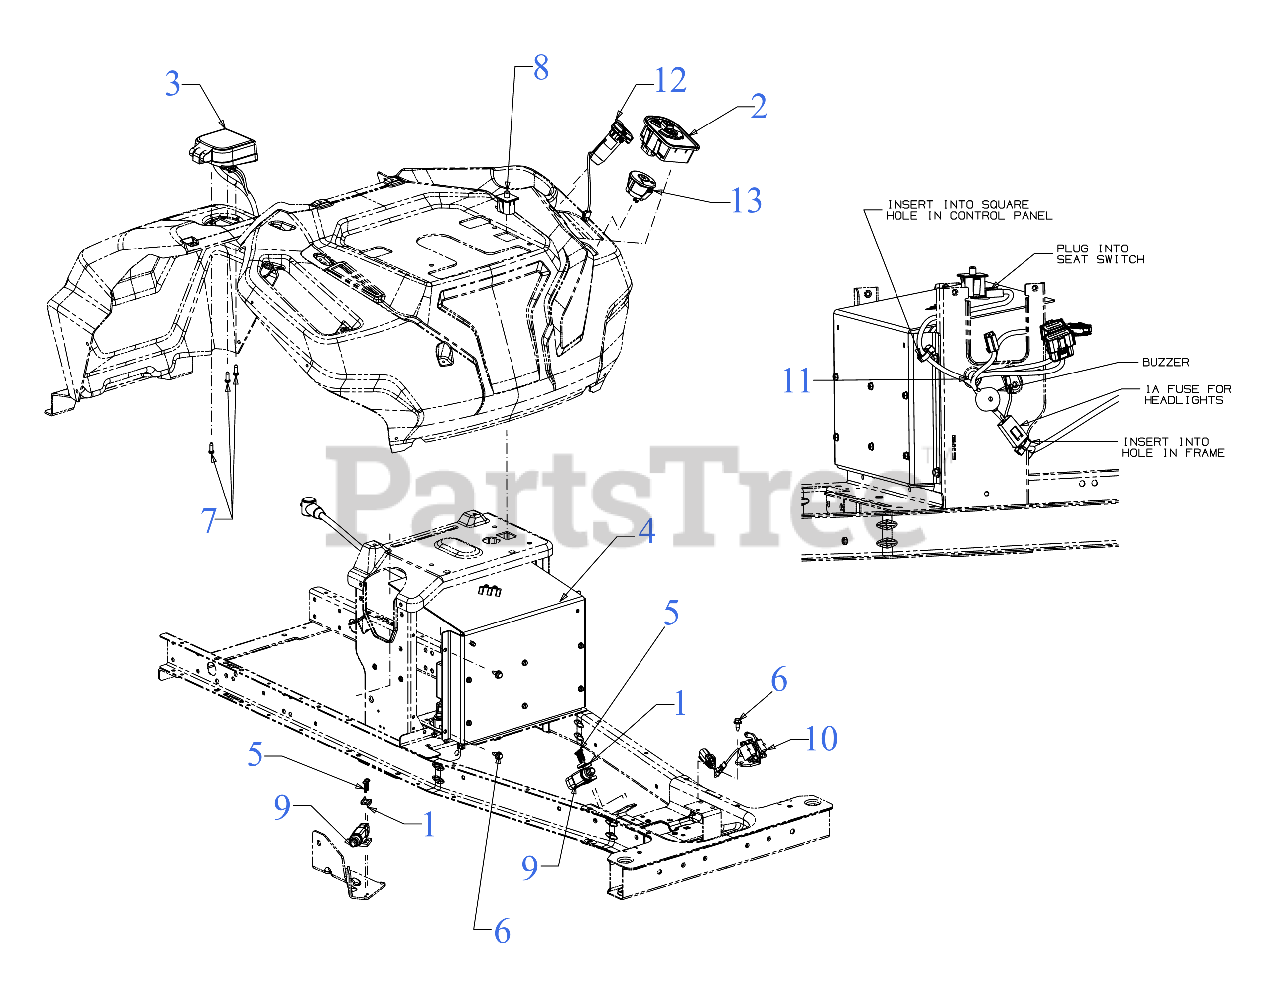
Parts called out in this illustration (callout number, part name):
1	PLATE-SWITCH
2	VCM MODULE
3	CHARGE PORT PLUG ASSEMBLY
4	MOTOR CONTROL PANEL
6	SCREW 1/4-20X.625
7	SCREW #12-16 x .625
8	SEAT SWITCH
9	PLUNGER SWITCH (NO/NO)
10	THROTTLE SENSOR (DUEL CLIP)
11	MAIN HARNESS (VCM HPD BATTERY)
12	USB RECEPTACLE (12V W/JUMPER)
13	KEY SWITCH (2 POSITION)
